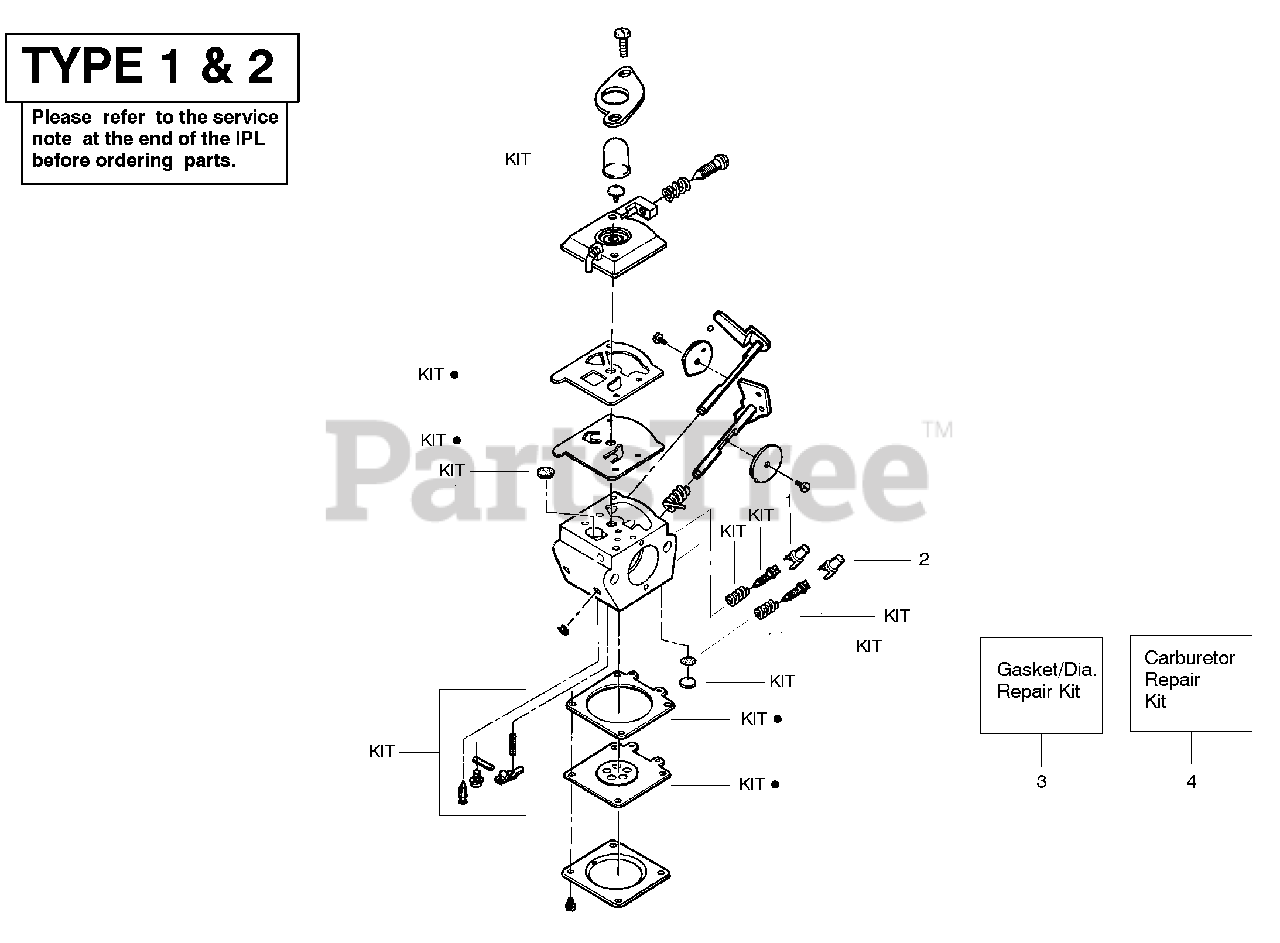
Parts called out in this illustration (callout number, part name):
1	Limiter Cap-Low (tan)
2	Limiter Cap-High (brown)
3	Gasket/Diaphragm Kit
4	Carburetor Repair Kit (KIT = Indicates Contents)
